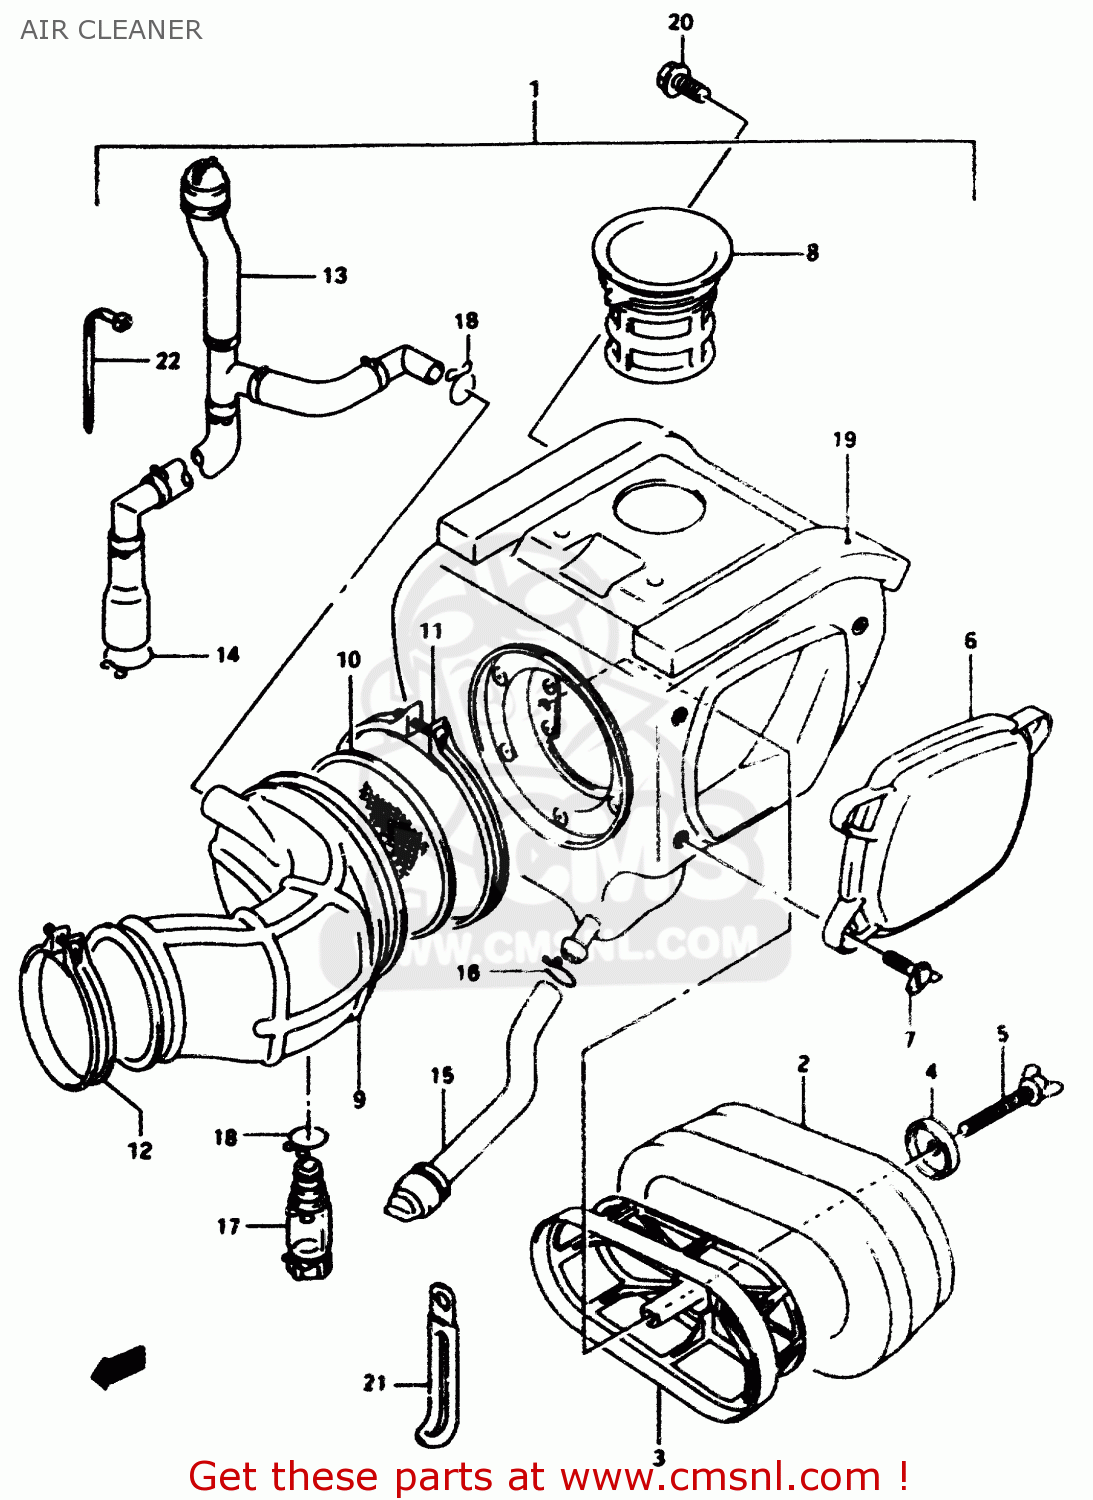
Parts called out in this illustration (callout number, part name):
1	CLEANER ASSY,AIR
2	FILTER
3	HOLDER,FILTER
4	WASHER,AIR CLEANER
5	BOLT,WING
6	CAP,AIR CLEANER
7	SCREW
8	TUBE,INLET
9	TUBE,OUTLET
10	TRAP,FRAME
11	CLAMP,OUTLET TUBE
12	CLAMP
13	TUBE,BREATHER
14	CLIP
15	TUBE,DRAIN A
16	CLIP
17	TUBE,DRAIN
18	CLIP
19	CUSHION
20	BOLT
21	CLAMP(L:80)
22	CLAMP L:165
